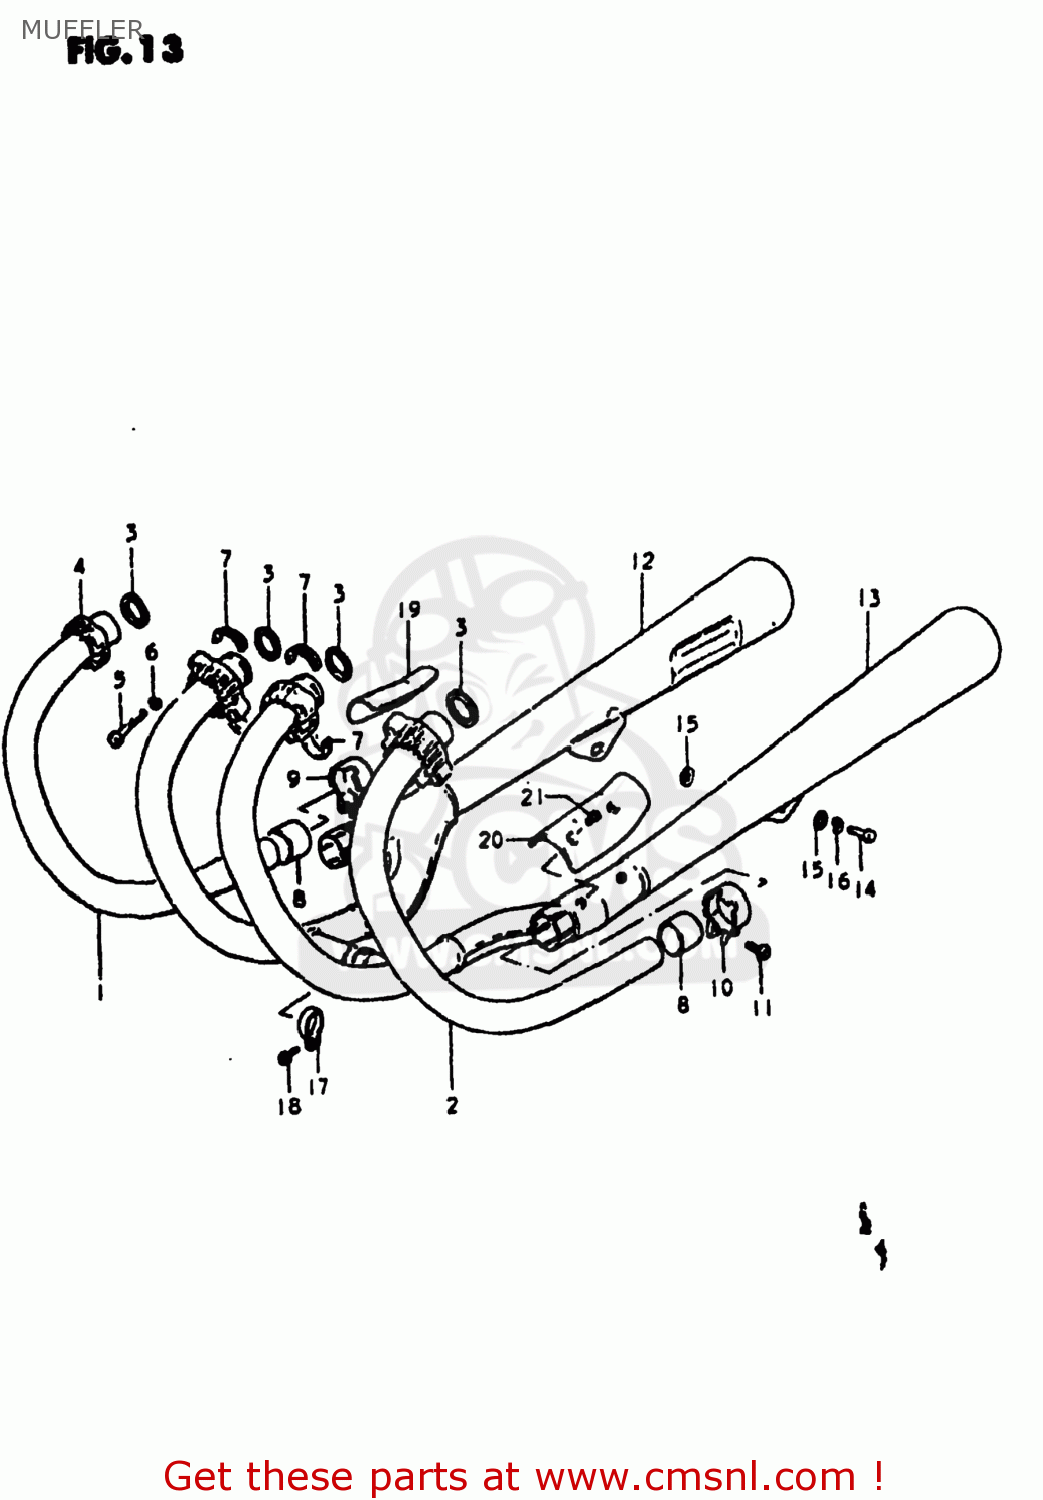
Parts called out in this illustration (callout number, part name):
1	PIPE,EXHAUST,R
2	PIPE,EXHAUST,L
3	GASKET,EXHAUST PIPE (NAS)
4	CLAMP,EXHAUST PIPE
5	BOLT
6	LOCK WASHER
7	PLATE,EXHAUST
8	CONNECTOR,MUFFLER
9	CLAMP,MUFFLER CONNECTOR,R
10	CLAMP,MUFFLER CONNECTOR,L
11	BOLT
12	BODY,MUFFLER
13	BODY,MUFFLER
14	BOLT 10X30
15	WASHER
16	LOCK WASHER
17	CLAMP
18	BOLT
19	COVER,MUFFLER,RIGHT
20	COVER,MUFFLER,LEFT
21	SCREW
